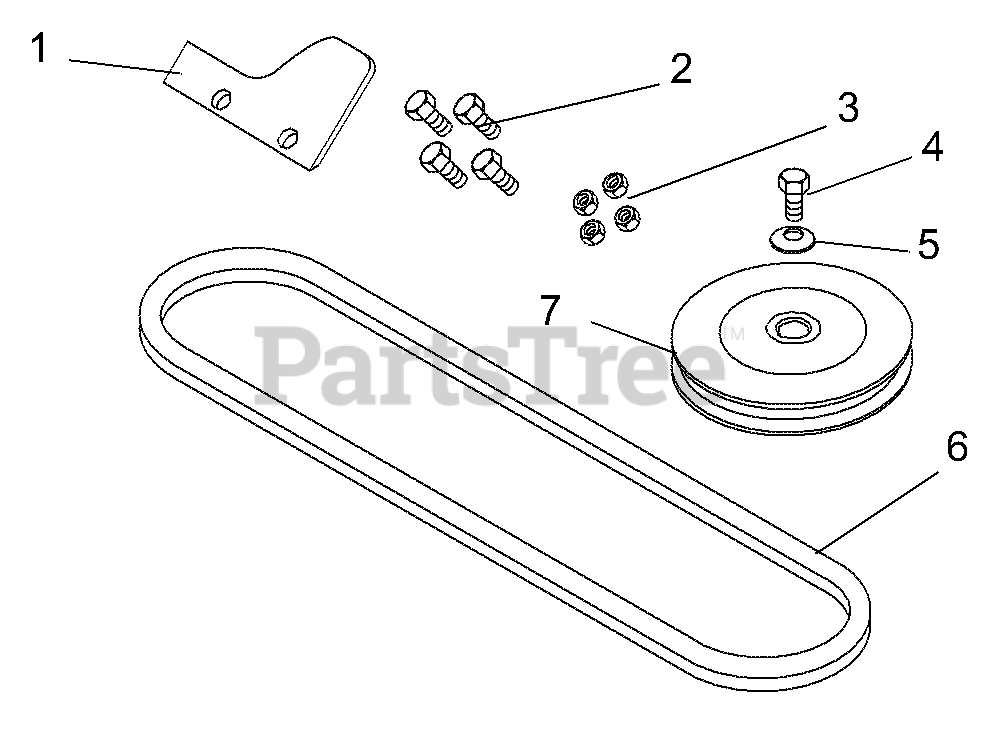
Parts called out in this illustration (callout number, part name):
2	BLT-HEX .31-24X.75 GR8 YWZC
3	NUT-CTRLK .31-24 YWZC
4	BLT-HEX .38-16X1.0 GR8 YZ EP30
5	WSHR,FLT STL.406X1.50X.245YWZC
6	V-BELT, HA-WRAPPED
7	SHEAVE, 4.25 DIA A-SECTION
7	SHEAVE, 4.75 DIA A-SECTION
7	KIT, 28" CUTTING IMPROVEMENT
7	KIT, 32" CUTTING IMPROVEMENT
